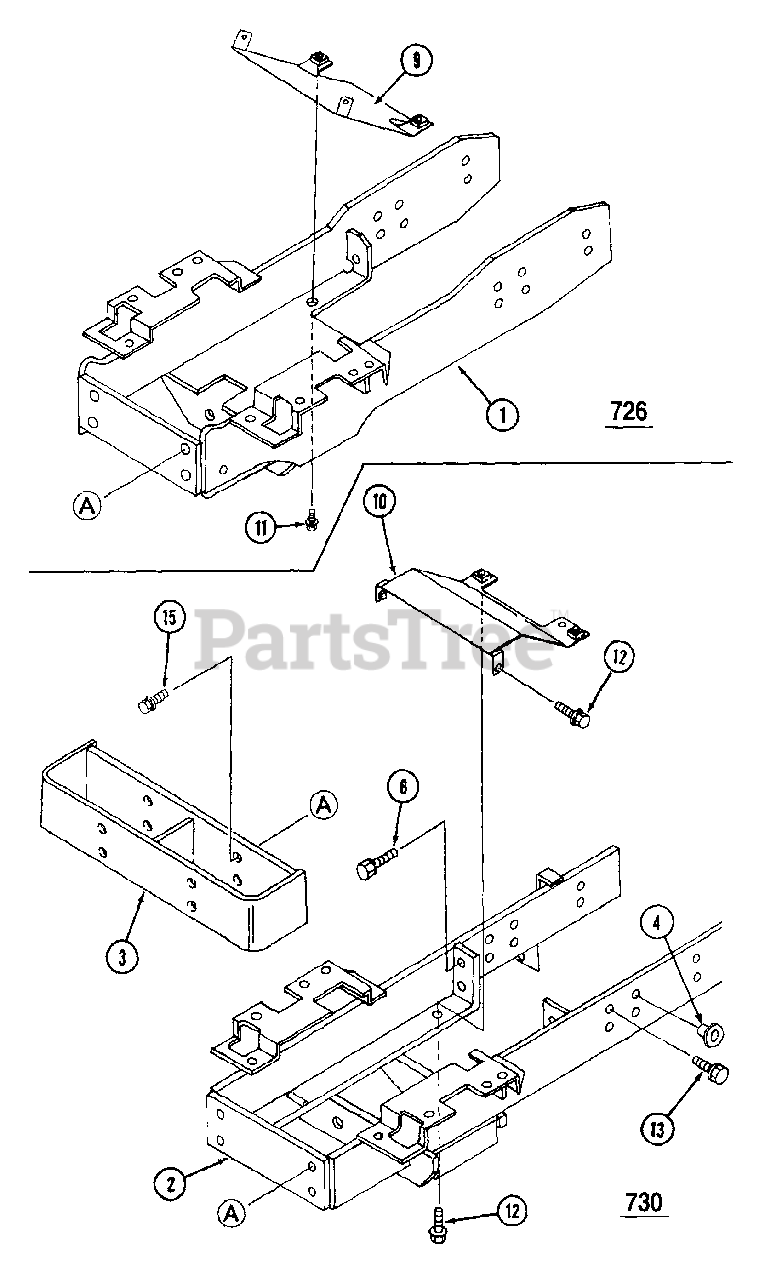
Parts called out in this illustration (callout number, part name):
1	Bracket, Front
2	Bracket, Front
3	Bracket, Weight
9	Cover
11	Bolt
